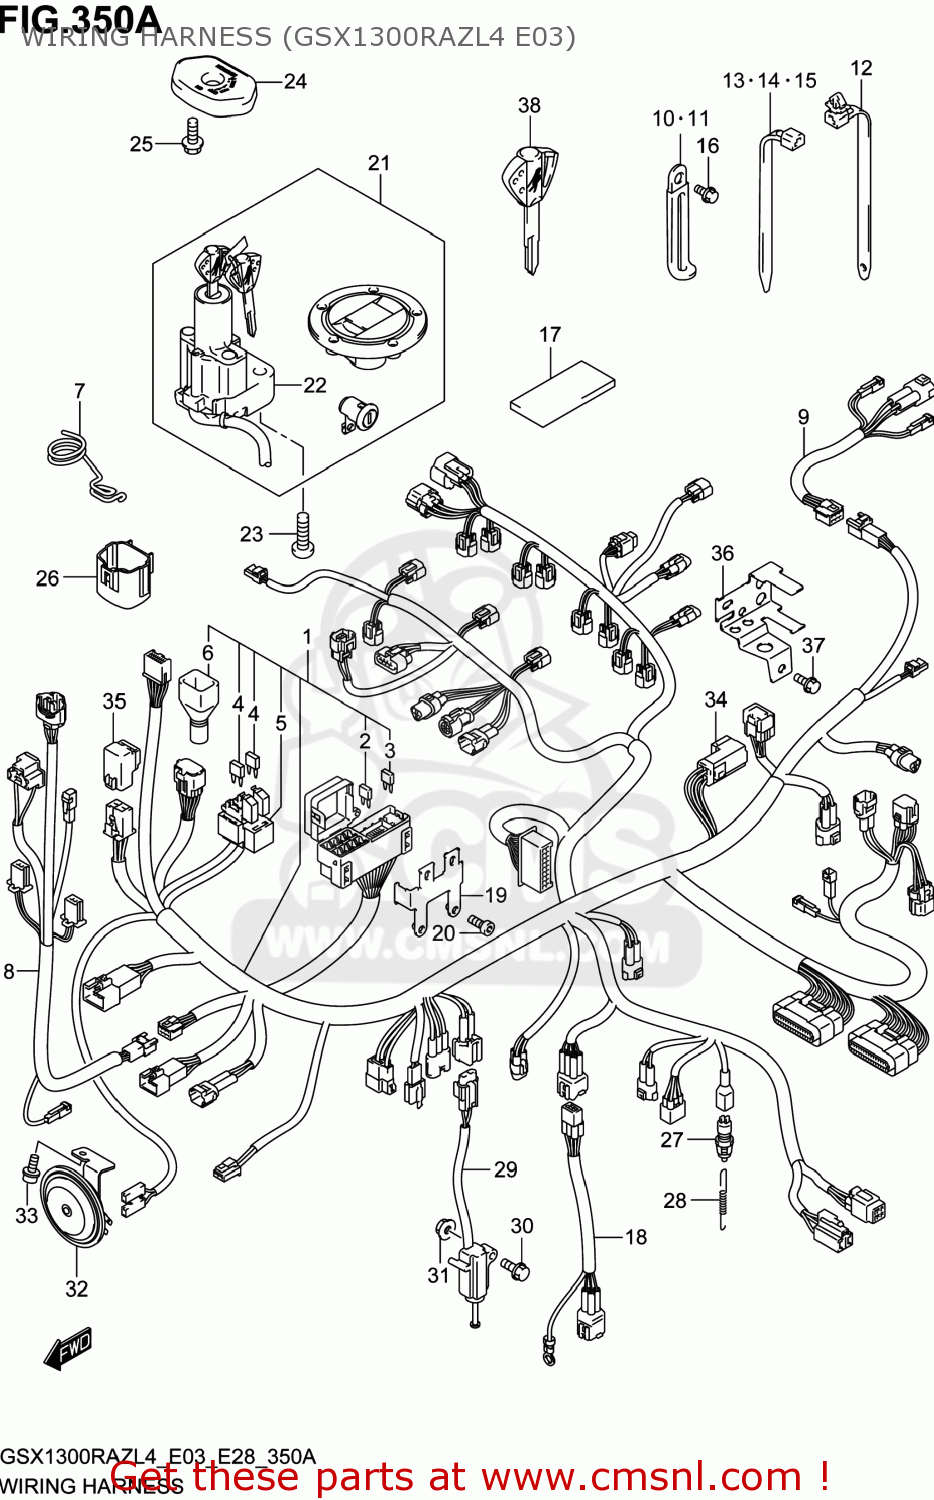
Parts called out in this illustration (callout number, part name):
1	HARNESS,WIRING
2	FUSE(10A)
3	FUSE(15A)
4	FUSE(15A)
5	HOLDER
6	COVER,SPEEDOMETER COUPLER
7	GUIDE,WIRING HARNESS
8	HARNESS,WIRING NO.2
9	WIRE,RR COMB
10	CLAMP(L:45)
11	CLAMP(L:135)
12	CLAMP(L:120)
13	CLAMP(L:125)
14	CLAMP(L:165)
15	CLAMP(L:145)
16	BOLT
17	PROTECTOR,WIRING HARNESS
18	WIRE,O2 SENSOR
19	BRACKET,FUSE BOX
20	BOLT
21	LOCK SET
22	LOCK ASSY,STEERING
23	BOLT(8X20)
24	COVER,STEERING LOCK
25	BOLT
26	CAP,TS
27	SWITCH ASSY,STOP LAMP
28	SPRING
29	SWITCH ASSY,SIDE STAND
30	BOLT(8X35)
31	NUT
32	HORN ASSY
33	BOLT
34	RELAY ASSY
35	RELAY ASSY
36	BRACKET,FUEL PUMP RLY
37	BOLT
38	KEY,BLANK
